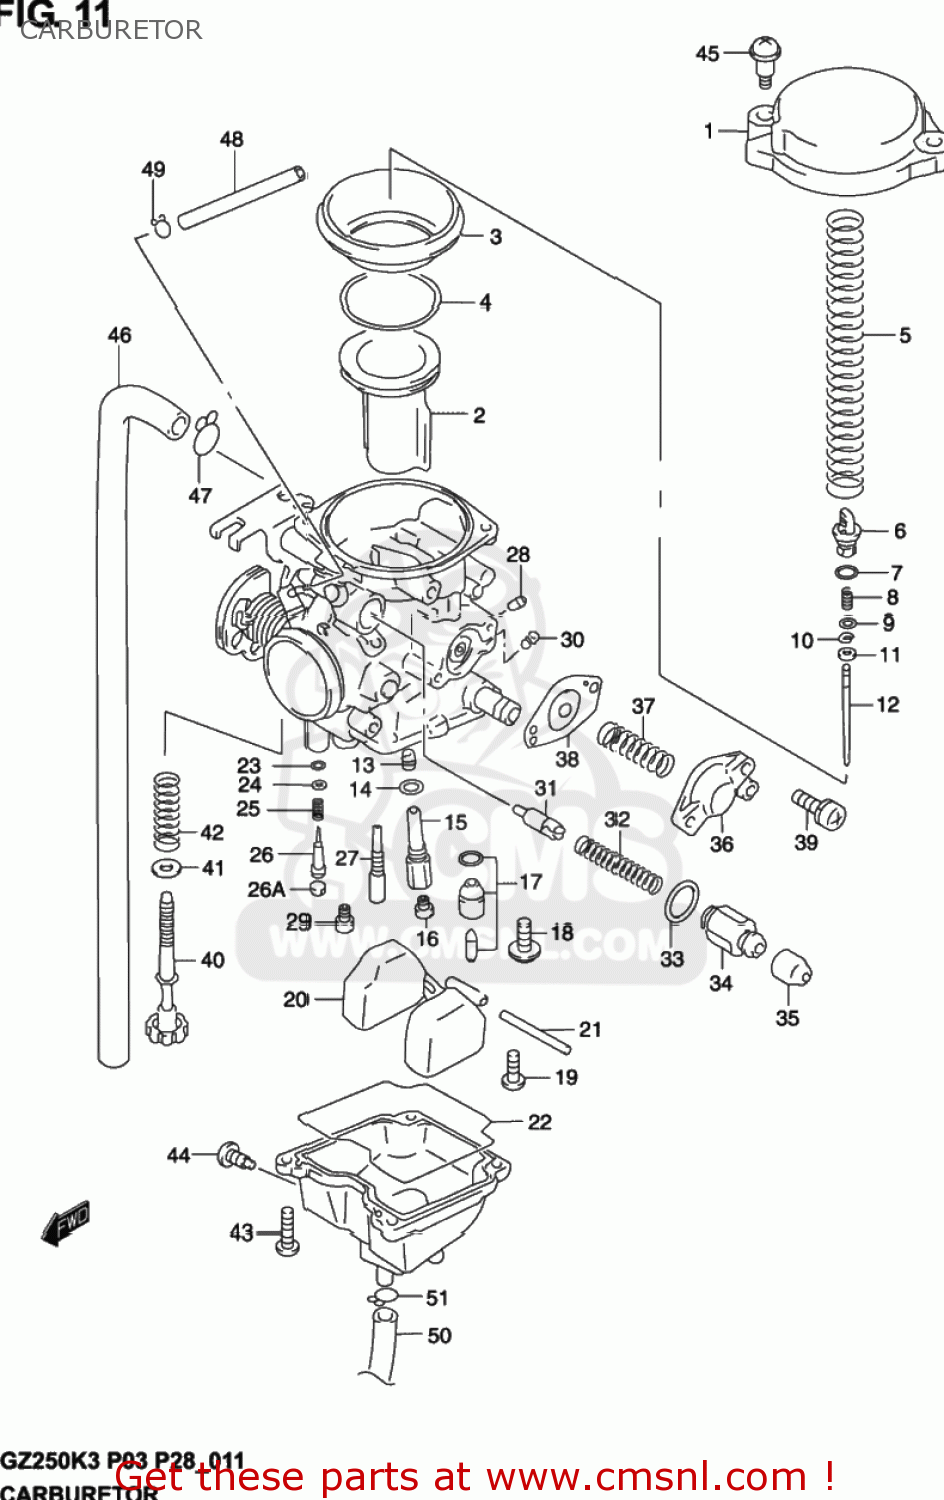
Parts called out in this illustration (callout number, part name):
1	COVER,DIAPHRAGM
2	VALVE,PISTON
3	DIAPHRAGM
4	RING
5	SPRING
6	HOLDER
7	O RING(D:1.9,ID:4.8)
8	SPRING
9	WASHER
10	E RING,MULTIPLE JET NOZZLE
11	RING
12	NEEDLE,JET
13	JET,NEEDLE(P-0M)
14	O RING
15	HOLDER,JET
16	JET,MAIN(120)
17	VALVE ASSY,NEEDLE
18	SCREW
19	SCREW
20	FLOAT ASSY
21	PIN,FLOAT
22	GASKET (NAS)
23	O RING,PILOT AIR SCREW
24	WASHER
25	SPRING,THROTTLE SCREW
26	ADJUSTER
26A	PLUG
27	JET,PILOT(17.5)
28	JET,MAIN(87.5)
29	JET,MAIN(52.5)
30	JET,PILOT AIR(120)
31	PLUNGER
32	SPRING
33	O RING
34	HOLDER,GUIDE
35	CAP
36	COVER ASSY
37	SPRING
38	DIAPHRAGM ASSY
39	SCREW
40	SCREW,ADJUST
41	PACKING (NAS)
42	SPRING
43	SCREW
44	PLUG,DRAIN
45	SCREW
46	HOSE
47	CLIP
48	HOSE
49	CLIP
50	HOSE(4.5X8X650)
51	CLIP
